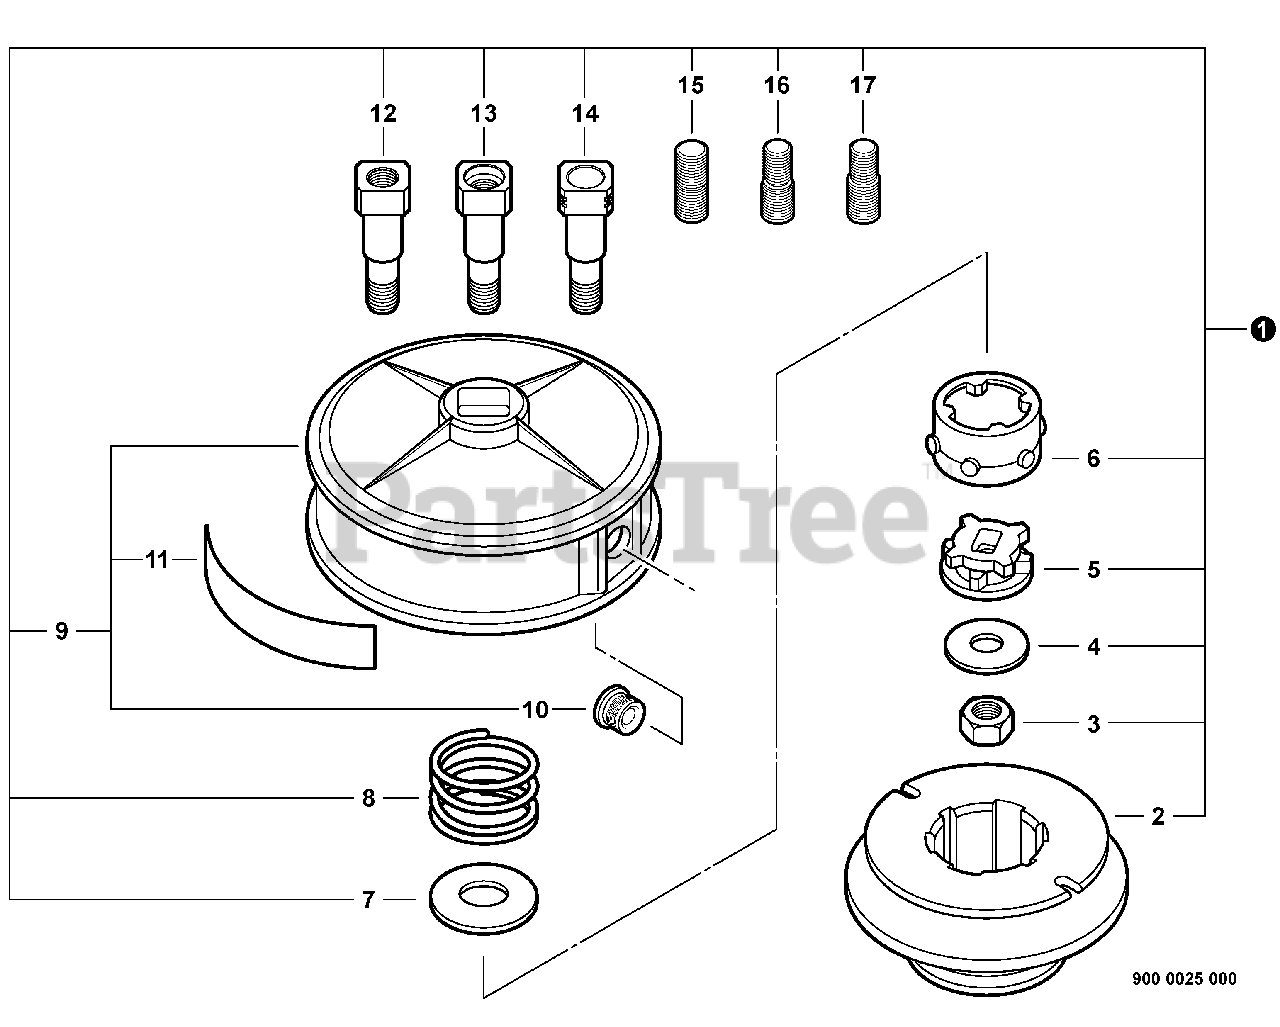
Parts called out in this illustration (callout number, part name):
1	SRM ECHOMATIC HEAD
3	LOCKNUT
4	WASHER - 8
5	CAM - INNER
6	DRIVE - OUTER
7	WASHER - 14
9	SPOOL COVER ASSY
11	LABEL - CAUTION
12	BOLT, SHAFT
13	BOLT, SHAFT
14	BOLT, SHAFT
15	STUD - BLACK
16	STUD - 8 -- SILVER
17	STUD - GOLD -- LEFT HAND
